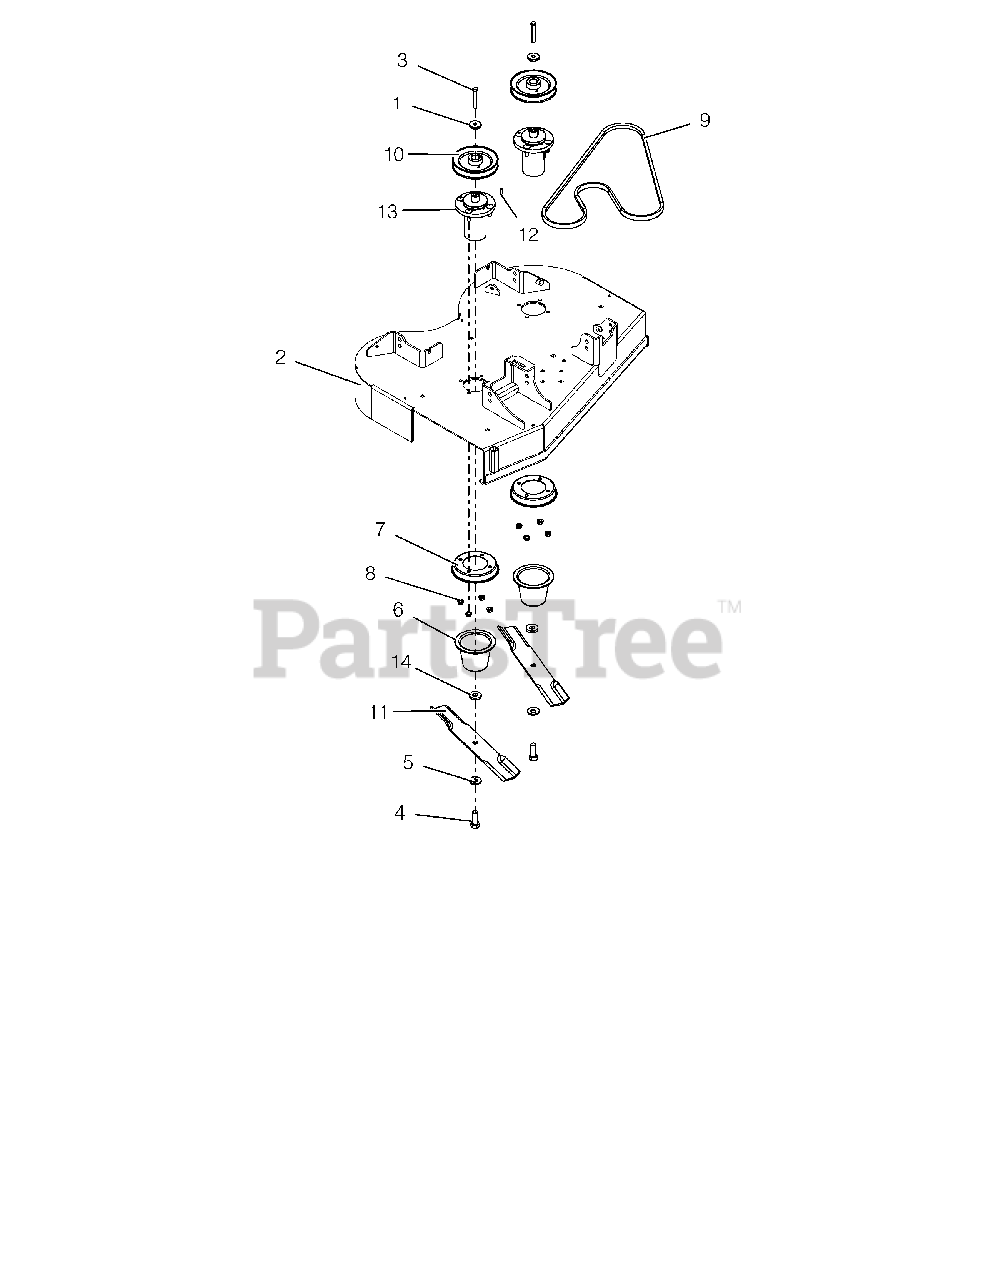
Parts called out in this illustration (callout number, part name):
1	RETAINER, SHEAVE
2	ASM, 36" DECK W/DECALS
3	BLT-HEX .38-16X2.75 GR8 YWZC
4	BLT-HEX .62-18X1.75 GR8 YWZC
5	WSHR-BLVL .669X1.535X.138
6	GUARD, SPINDLE LOWER
7	GUARD, SPINDLE TOP
8	NUT-LK-CTR-FLG .38-16 YWZC
9	BELT, 5L
10	PULLEY, V-1"ID X 5.75" OD
11	BLADE, 18.000 X .80 LIFT
12	KEY-STR .25X.75X.25
13	ASM, ALUMINUM SPINDLE (SHORT)
14	WSHR-FL-STL .630X1.50X.25 YWZC
